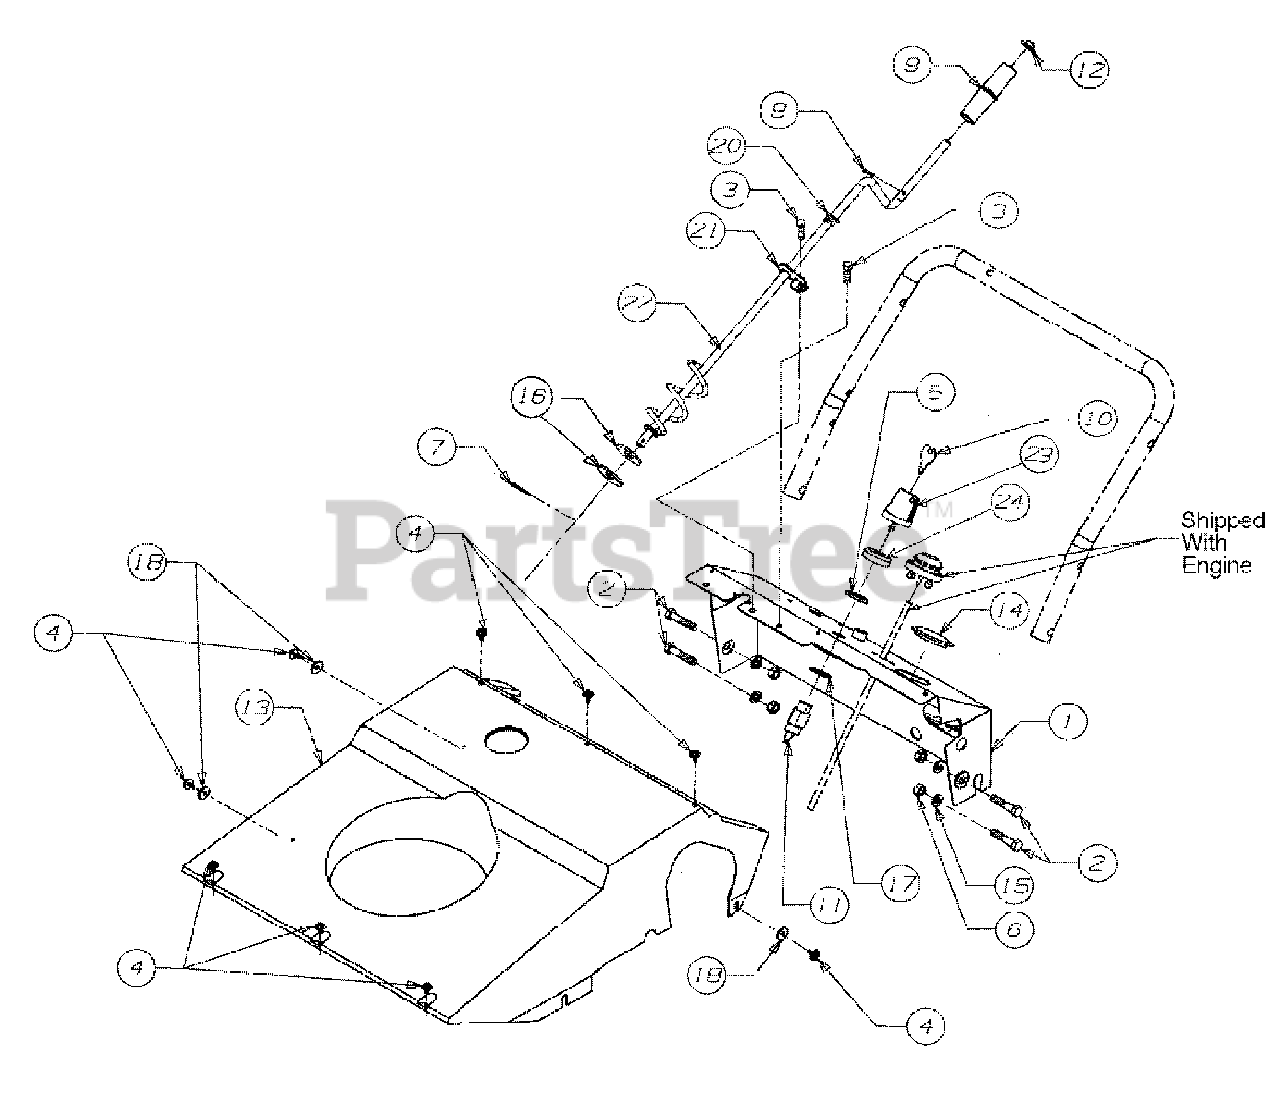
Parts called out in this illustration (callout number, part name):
1	Dash-21"
2	Screw-Hex
3	Screw-Hex Tap
4	Screw-Hex Tap
5	Nut Hex
6	Nut-Hex
7	Pin-Cotter
8	Pin Roll
9	Knob-Chute Crank
10	Key-Ignition - Std.
11	Switch-Key
12	Nut Push
13	Shroud-Grey
15	Washer Lock
16	Washer-Flat
17	Washer Internal Lock
18	Washer Flat
20	Bushing
21	Bracket Chute Crank
22	Crank Ass'y. Chute
23	Key-Ignition w/Bell Cover
24	Cover - Ignition Switch
